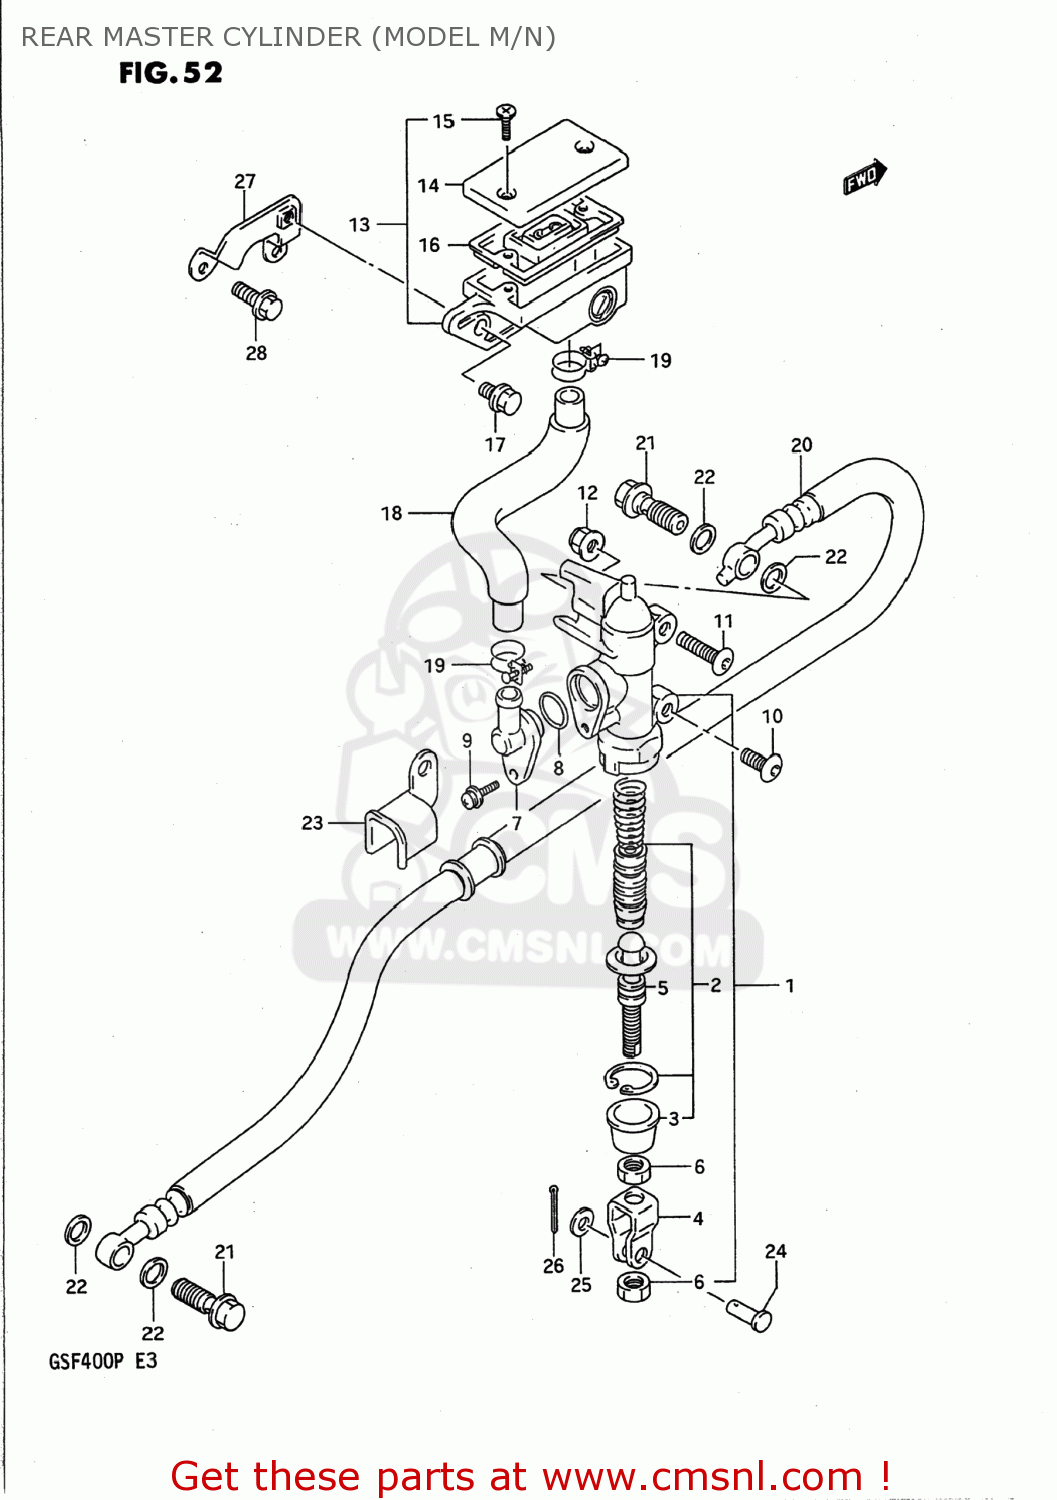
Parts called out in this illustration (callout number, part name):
1	CYLINDER ASSY,RR MASTER
2	PISTON/CUP SET
3	BOOT
4	YOKE
5	ROD,PUSH
6	NUT
7	CONNECTOR
8	O RING
9	SCREW
10	SCREW(6X16)
11	SCREW(6X30)
12	NUT
13	TANK ASSY,RR RESERVOIR
14	CAP
15	SCREW
16	17
17	BOLT 6X12
18	HOSE,RESERVOIR TANK
19	CLAMP
20	HOSE,REAR BRAKE
21	BOLT UNION
22	WASHER(10X15X1.5)
23	GUIDE,BRAKE HOSE
24	PIN
25	WASHER
26	PIN
27	PLATE,REAR RESERVOIR TANK
28	BOLT
